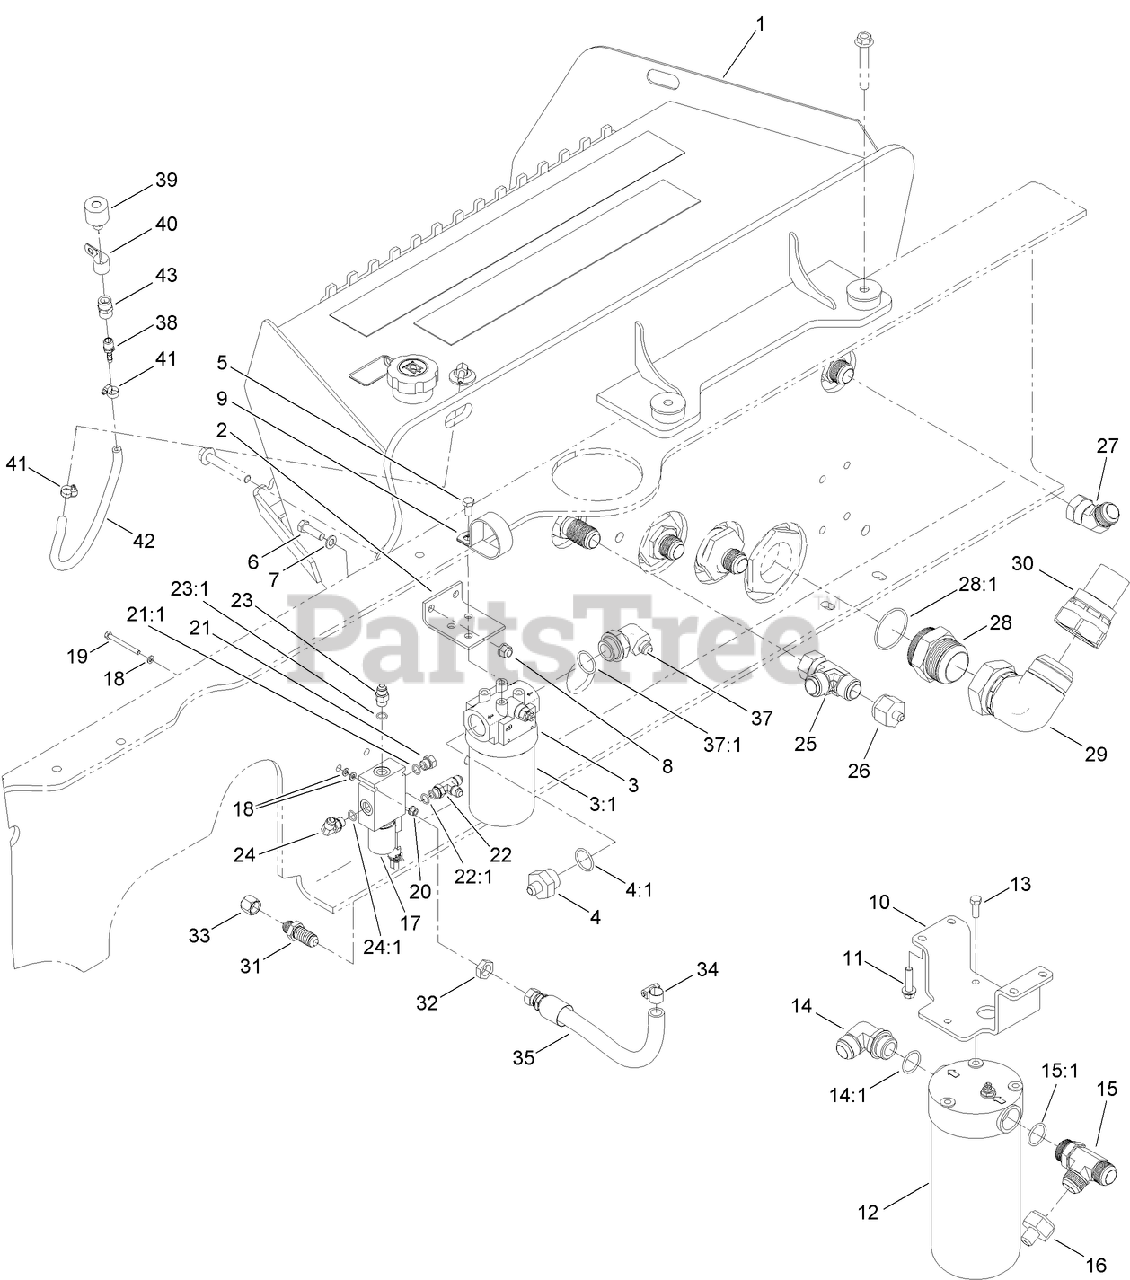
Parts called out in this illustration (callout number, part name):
1	HYD TANK ASM
2	BRACKET-MOUNTING, FILTER
3	OIL FILTER ASM
3:1	FILTER-HYD
4	CONNECTOR ASM
4:1	O-RING
5	SCREW-HH
6	Screw-HH
7	WASHER-FLAT
8	NUT-LOCK, NI
9	CLAMP-R
10	BRACKET-FILTER
11	SCREW-HHF
12	HYD RETURN FILTER ASM
13	SCREW-HH
14	ELBOW-90 DEG
14:1	O-RING
15	FITTING-TEE
15:1	O-RING
16	ADAPTER-REDUCER
17	SOLENOID VALVE ASM
18	WASHER-FLAT
19	SCREW-HH
20	NUT-FLANGE, NI
21	PLUG-HH
21:1	O-RING
22	FITTING-TEE
22:1	O-RING
23	FITTING-STRAIGHT
23:1	O-RING
24	FITTING-ELBOW, 90 DEG
24:1	O-RING
25	TEE-SWIVEL
26	REDUCER
27	FITTING-ELBOW, 45
28:1	O-RING(3-932)
29	ADAPTER-90 DEG
30	FITTING-STRAIGHT
32	NUT-LOCK
34	CLAMP-HOSE, WORM DRIVE
35	HYD HOSE ASM, LP
37	FITTING-ELBOW, 90
37:1	O-RING
38	FITTING-STRAIGHT
39	BREATHER
40	CLAMP-R
41	CLAMP-WORM
42	HOSE-FUEL
43	COUPLING-PIPE (NPTF)
